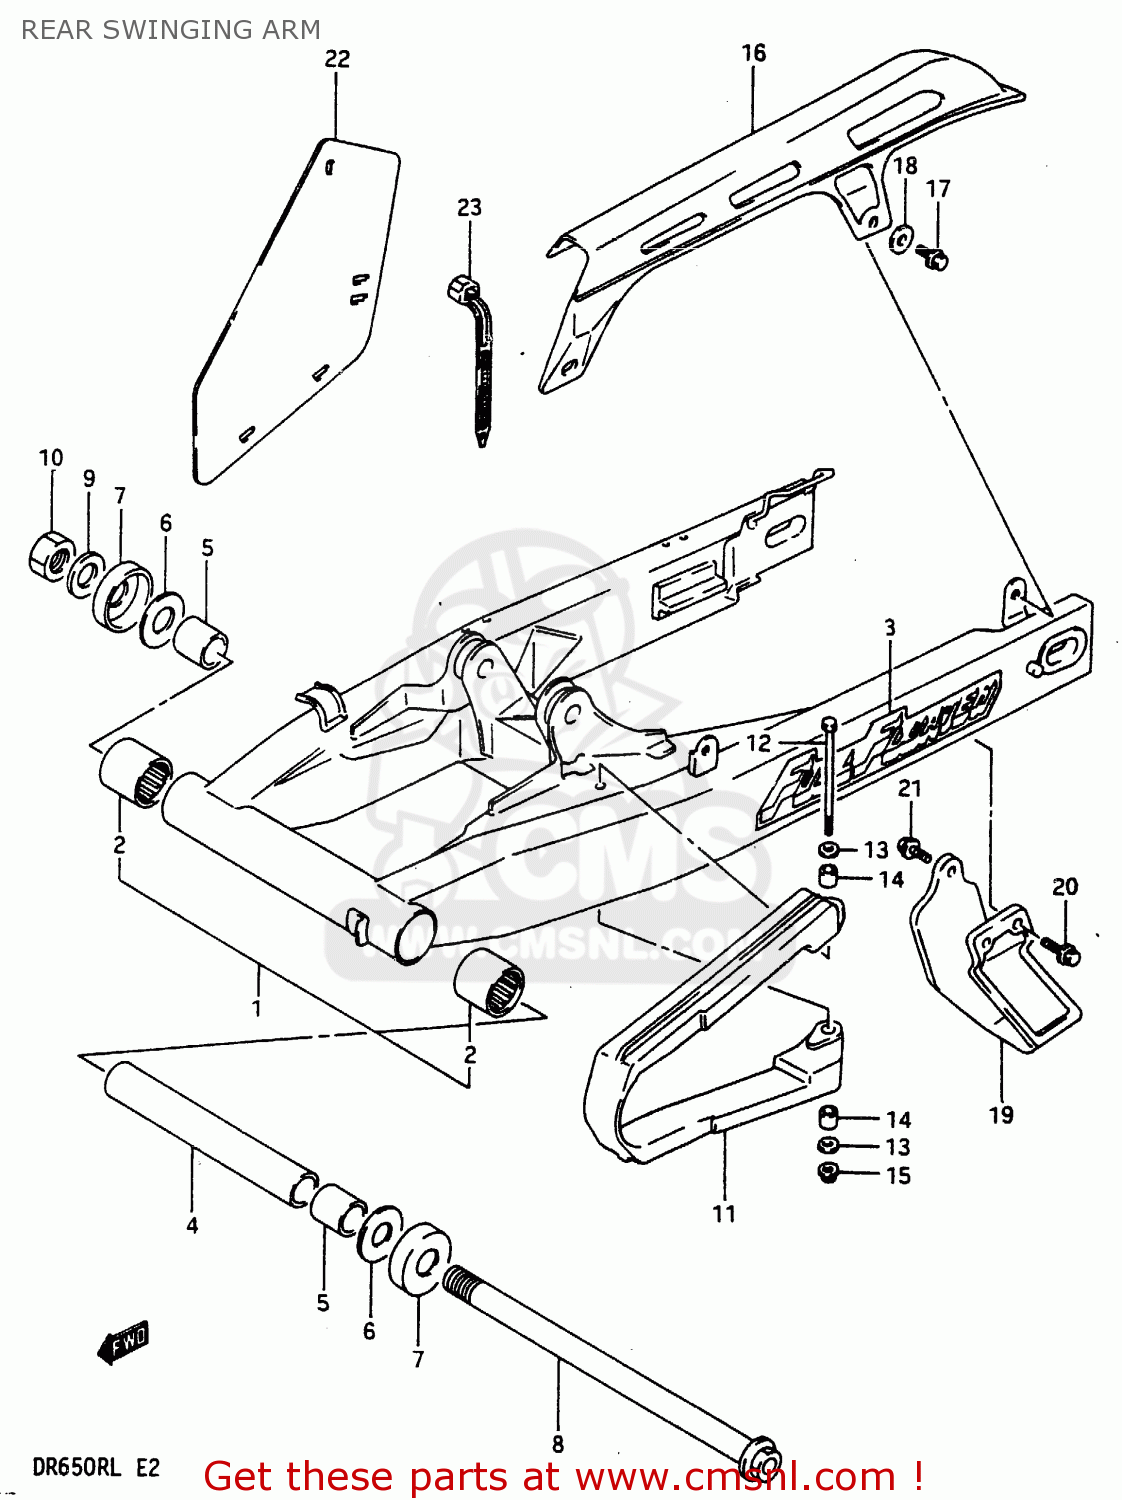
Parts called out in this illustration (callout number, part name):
1	SWING ARM ASSEMBLY,REAR
2	BEARING(22X29X20)
3	EMBLEM
4	SPACER,RR SWGARM PIVOT CTR
5	SPACER,RR SWGARM PIVOT
6	WASHER
7	SEAL,RR SWGARM PIVOT DUST
8	SHAFT,REAR SWING ARM
9	WASHER (BLACK)
10	NUT (BLACK)
11	BUFFER,CHAIN TOUCH DEFLECTOR
12	BOLT,TOUCH DEFENSE FTG
13	WASHER (5.5X14X1.2)
14	SPACER (6.6X9X6.5)
15	NUT
16	CASE,CHAIN
17	BOLT
18	WASHER
19	GUIDE,CHAIN
20	BOLT
21	BOLT 6X16
22	GUARD, CHAIN
23	CLAMP(L:125)
